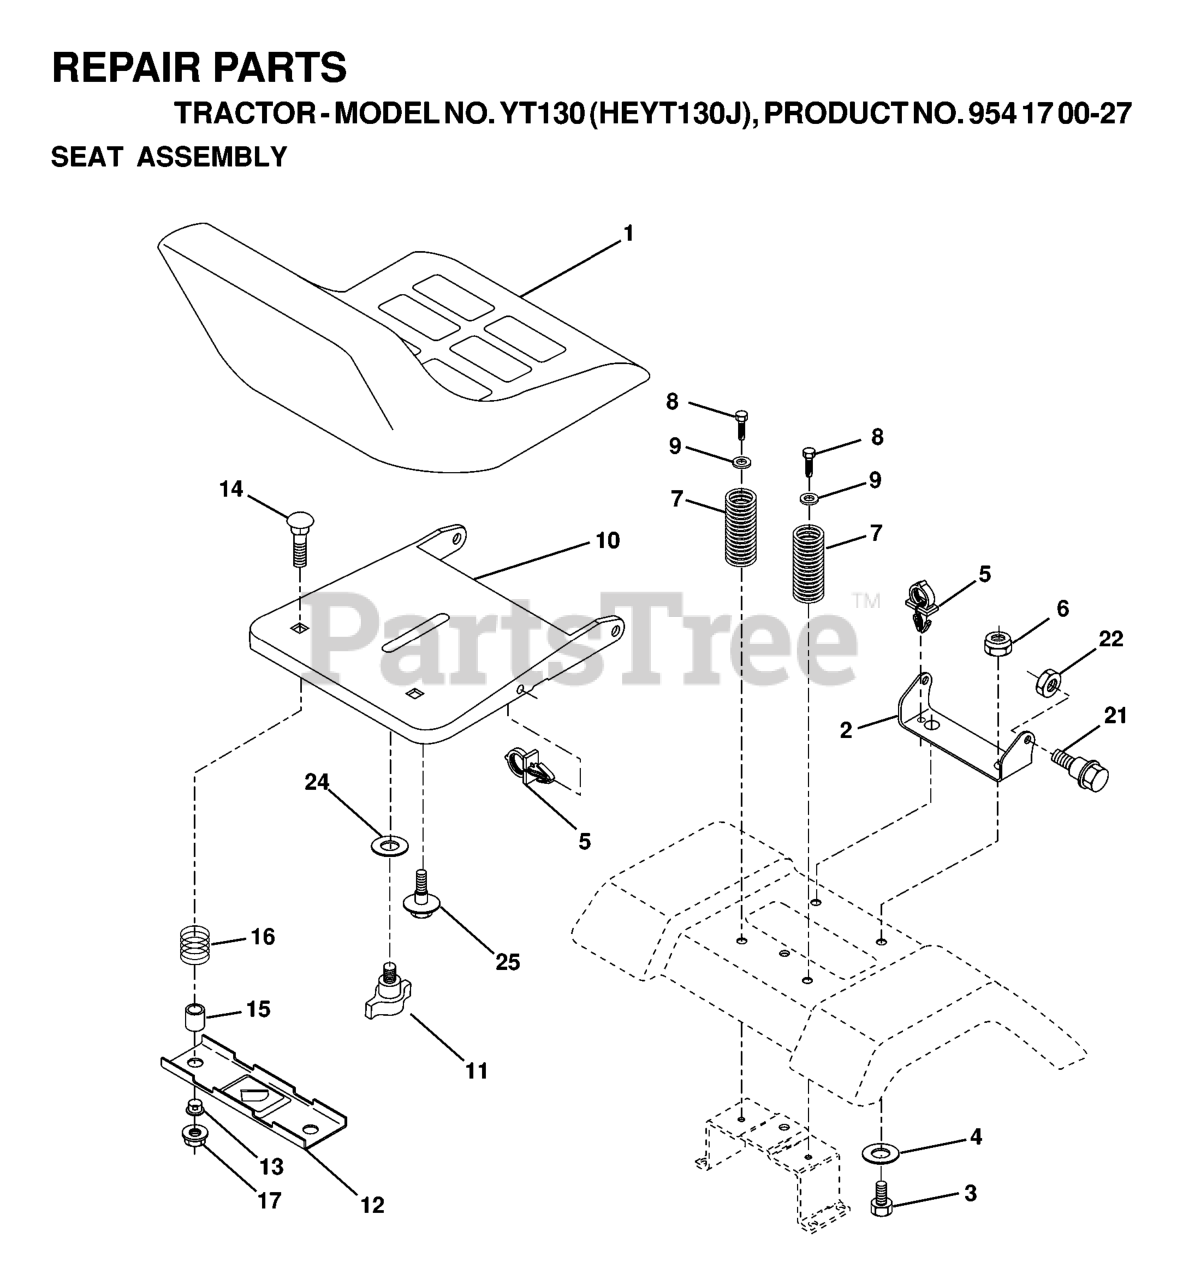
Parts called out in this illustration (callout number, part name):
1	SEAT, GRAY
2	SEAT PIVOT BRKT
3	BOLT
6	NUT
7	SPRING COMPRESSION
8	SCREW THDROL 3/8-16 X 1-1/2
9	WASHER
10	PAN, SEAT
11	KNOB.SEAT.ADJ.WINGNUT
12	BRKT SWITCH
14	BOLT.ROUND.HEAD.SQUARE.NECK
15	SPACER SPLIT 28X.96
17	NUT T
21	BOLT SHOULDER 5/16-18
22	NUT.71038.31-18.HEX.NYLOCK
24	WASHER GT
25	BOLT,SHOULD
